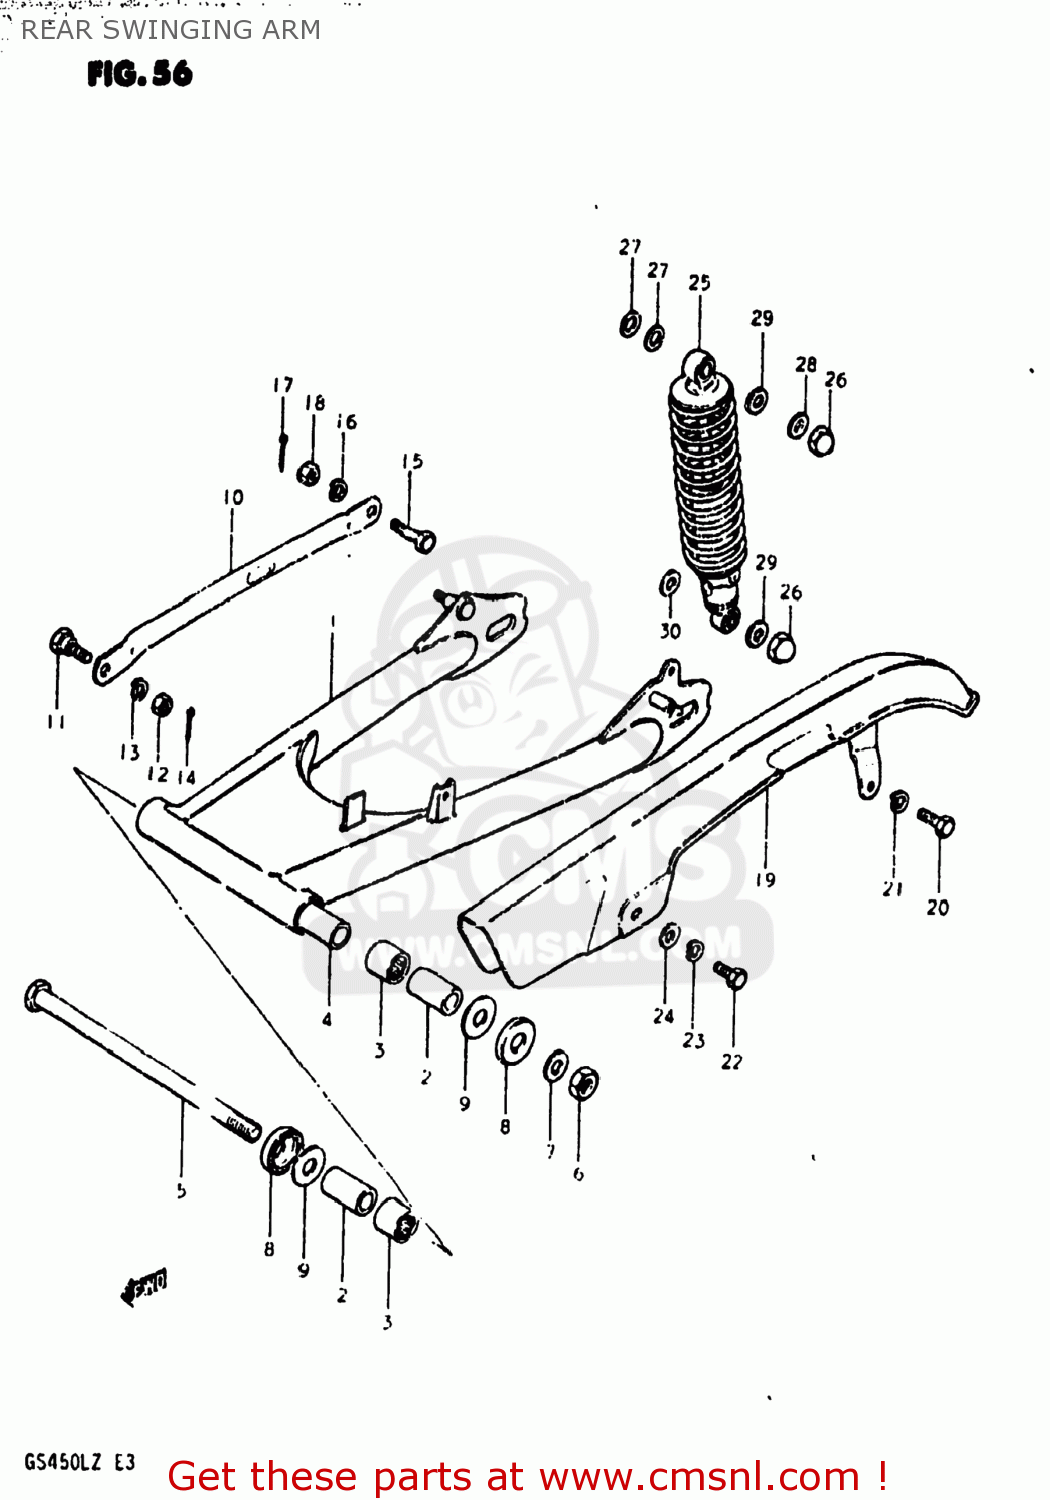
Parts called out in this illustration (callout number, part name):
1	ARM,REAR SWING
2	SPACER,RR SWGARM PIVOT
3	BEARING(22X29X30)
4	SPACER,SWINGINGARM CTR
5	SHAFT,REAR SWING ARM
6	NUT 14MM
7	WASHER
8	COVER,REAR SWING ARM DUST
9	WASHER(14.2X34X1)
10	LINK,REAR TORQUE
11	BOLT(10X24.5)
12	NUT
13	LOCK WASHER
14	PIN 20X20
15	BOLT(10X31)
16	LOCK WASHER
17	PIN 20X20
18	NUT
19	CASE,CHAIN
20	BOLT, UPPER
21	LOCK WASHER
22	BOLT
23	LOCK WASHER
24	WASHER
25	ABSORBER ASSEMBLY,REAR SHOCK
26	NUT, LOWER LH
27	WASHER
28	WASHER
29	WASHER(10.5X24X3.2)
30	WASHER (12.5X24X1.6)
